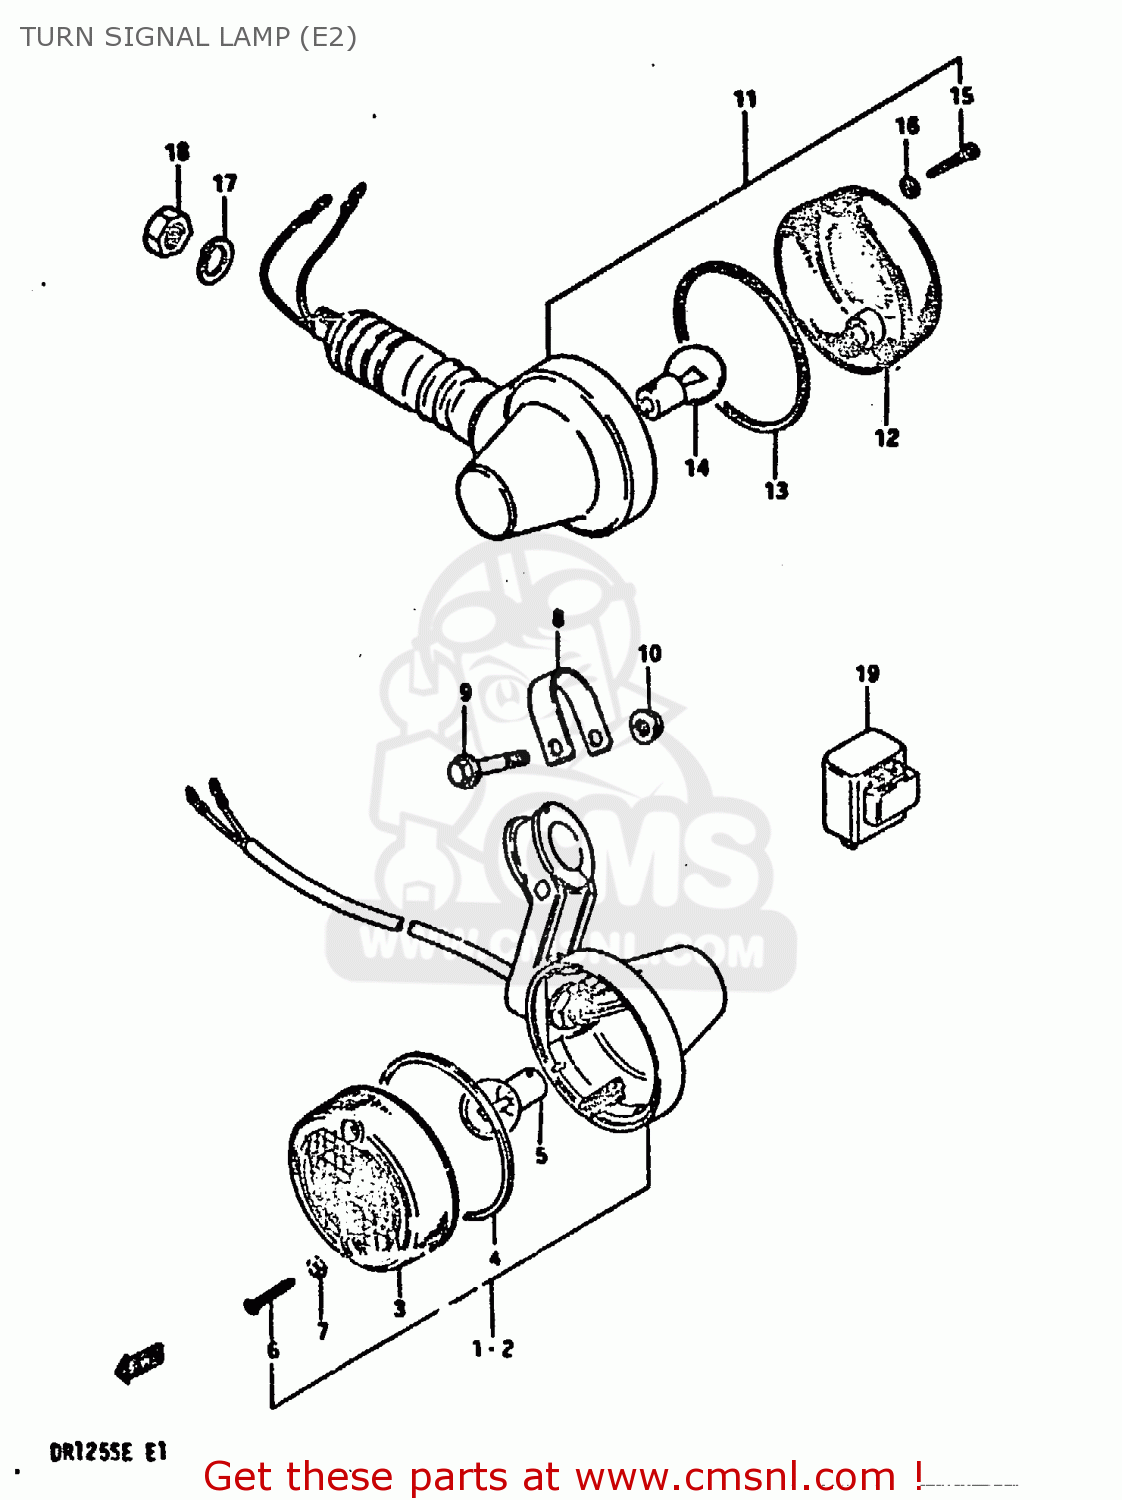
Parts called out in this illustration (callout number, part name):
1	LAMP, FRONT TURN SIGNAL RH
2	LAMP, FRONT TURN SIGNAL LH
3	LENS
4	GASKET
5	BULB(12V21W)
6	SCREW TAPP.
7	GASKET (NAS)
8	PLATE
9	BOLT 5X42
10	NUT
11	LAMP, REAR TURN SIGNAL
12	LENS
13	GASKET (NAS)
14	BULB(12V21W)
15	SCREW TAPP.
16	GASKET (NAS)
17	WASHER,LOCK 12
18	NUT
19	RELAY ASSEMBLY,TURN SIGNAL
